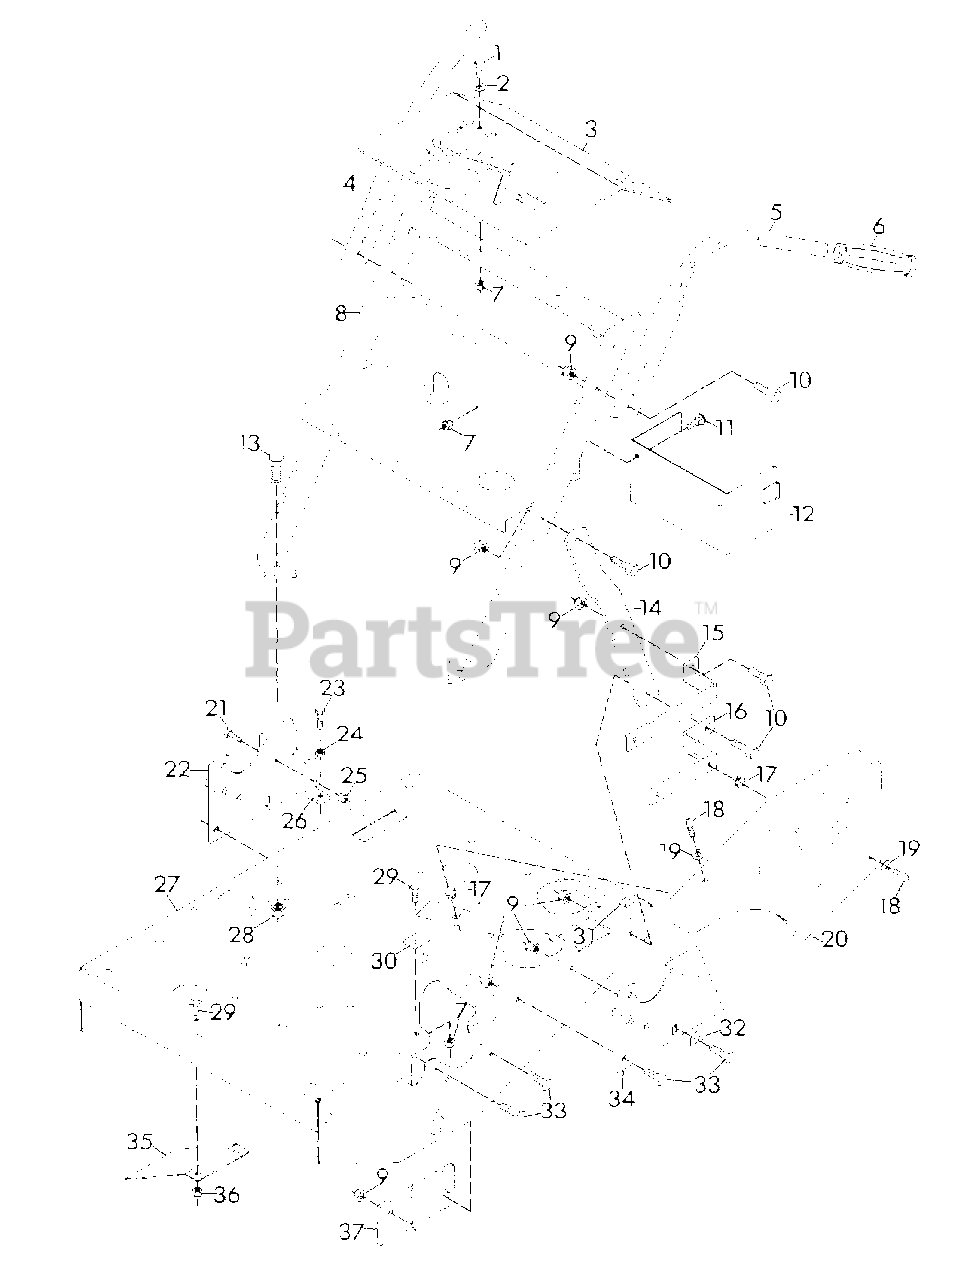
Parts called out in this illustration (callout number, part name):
1	BOLT, HEX 5/16-18X1.00
2	WASHER, FLAT .344X.688X.065
3	PLATE, SILK SCREEN
4	HANDLEBAR, R.H.
5	HANDLEBAR, L.H.
6	GRIP, HANDLEBAR
7	NUT, LOCK 5/16-18
8	WELDMENT, HANDLEBAR SUPPORT
9	NUT, LOCK 3/8-16
10	BOLT, HEX 3/8-16X1.25
11	BOLT, 5/16-18X.625 RD HD SQ NK
12	WELDMENT, BATTERY BOX
13	BOLT, HEX 1/2-13X1.25
14	BRACE, HANDLEBAR SUPPORT
15	BRACKET, TOP
16	BRACKET, BOTTOM
17	GROMMET, PLASTIC
18	SCREW, MACHINE 1/4-20X.625 RD HD
19	WASHER, FLAT .281X.625X.065
20	GUARD, BELT L.H.
20	GUARD, BELT R.H.
21	BOLT, HEX 1/4-20X.625
22	WELDMENT, BEARING SUPPORT R.H.
23	BOLT, HEX 1/4-20X1.00
24	NUT, HEX 1/4-20
25	NUT, LOCK 1/4-20
26	BRACKET
27	FRAME, PRO
28	NUT, LOCK 1/2-13
29	BOLT, HEX 5/16-18X.75
30	SUPPORT, FRONT L.H.
30	SUPPORT, FRONT R.H.
31	STOP
32	WASHER, FLAT .406X.812X.065
33	BOLT, HEX 3/8-16X1.00
34	WELDMENT, BEARING SUPPORT L.H.
35	BRACE
36	NUT, LOCK 5/16-18
37	WELDMENT, BRAKE PIN PLATE L.H.
37	WELDMENT, BRAKE PIN PLATE R.H.
NS	DECAL, AMERICA
